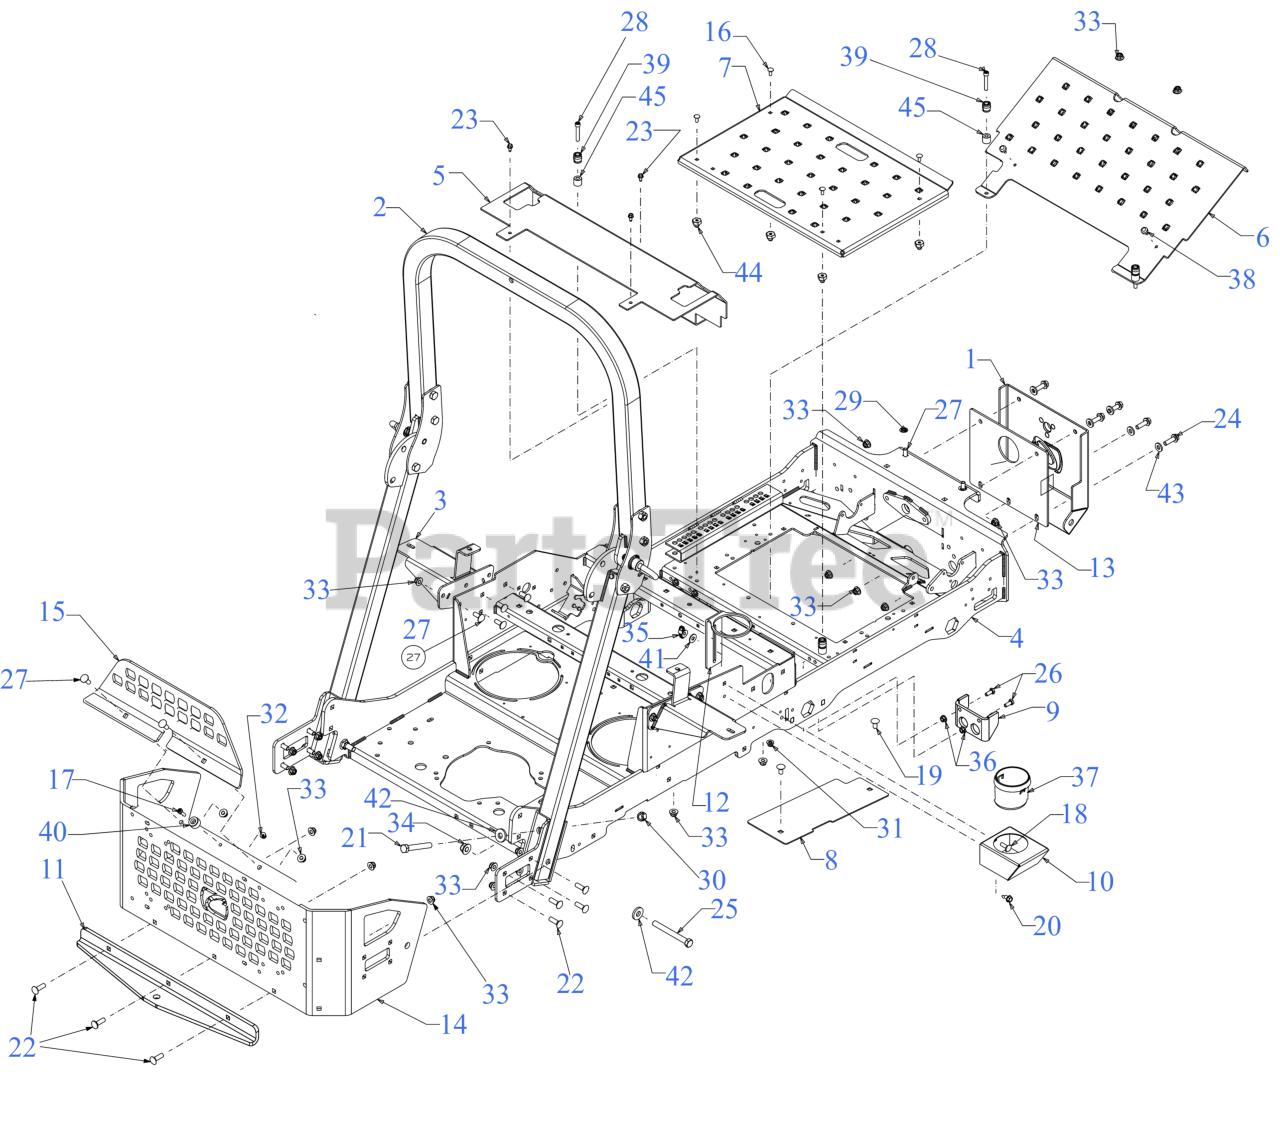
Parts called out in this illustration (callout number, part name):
2	PRO Z ROPS KIT
3	FUEL TANK MOUNT
4	FRAME ASSEMBLY
13	FRONT MOUNTING PLATE SPACER
14	BUMPER (LOWER RR)
15	BUMPER (UPPER RR)
16	CARRIAGE BOLT 1/4-20 x .62
17	MACHINE SCREW 1/4-20:1
18	CARRIAGE BOLT 5/16-18 x 1.00
19	CARRIAGE BOLT 3/8-16 x .750 GR5
20	SCREW 5/16-18 x .750
21	SCREW 1/2-20 x 3.50 GR5
22	CARRIAGE BOLT 3/8-16 X1.25 GR5
23	SCREW 1/4-20 X.500
24	SCREW 3/8-16 x 1.25 GR5
25	SCREW 1/2-13 x 4.5 GR 5
26	SCREW 5/16-18 x .75 GR5
27	CARRIAGE BOLT 3/8-16 x 1.00 GR5
28	SCREW 5/16-18X1.75 GR5
31	FLANGE LOCK NUT 5/16-18
32	FLANGE LOCK NUT
35	WING NUT 5/16-18
36	FLANGE NUT
38	BUMPER, .62 DIA x .3
39	RADIAL BUMPER
41	FLAT WASHER
42	FLAT WASHER .531 x 1.25 x .181
43	FLAT WASHER
44	SHOULDER SPACER
